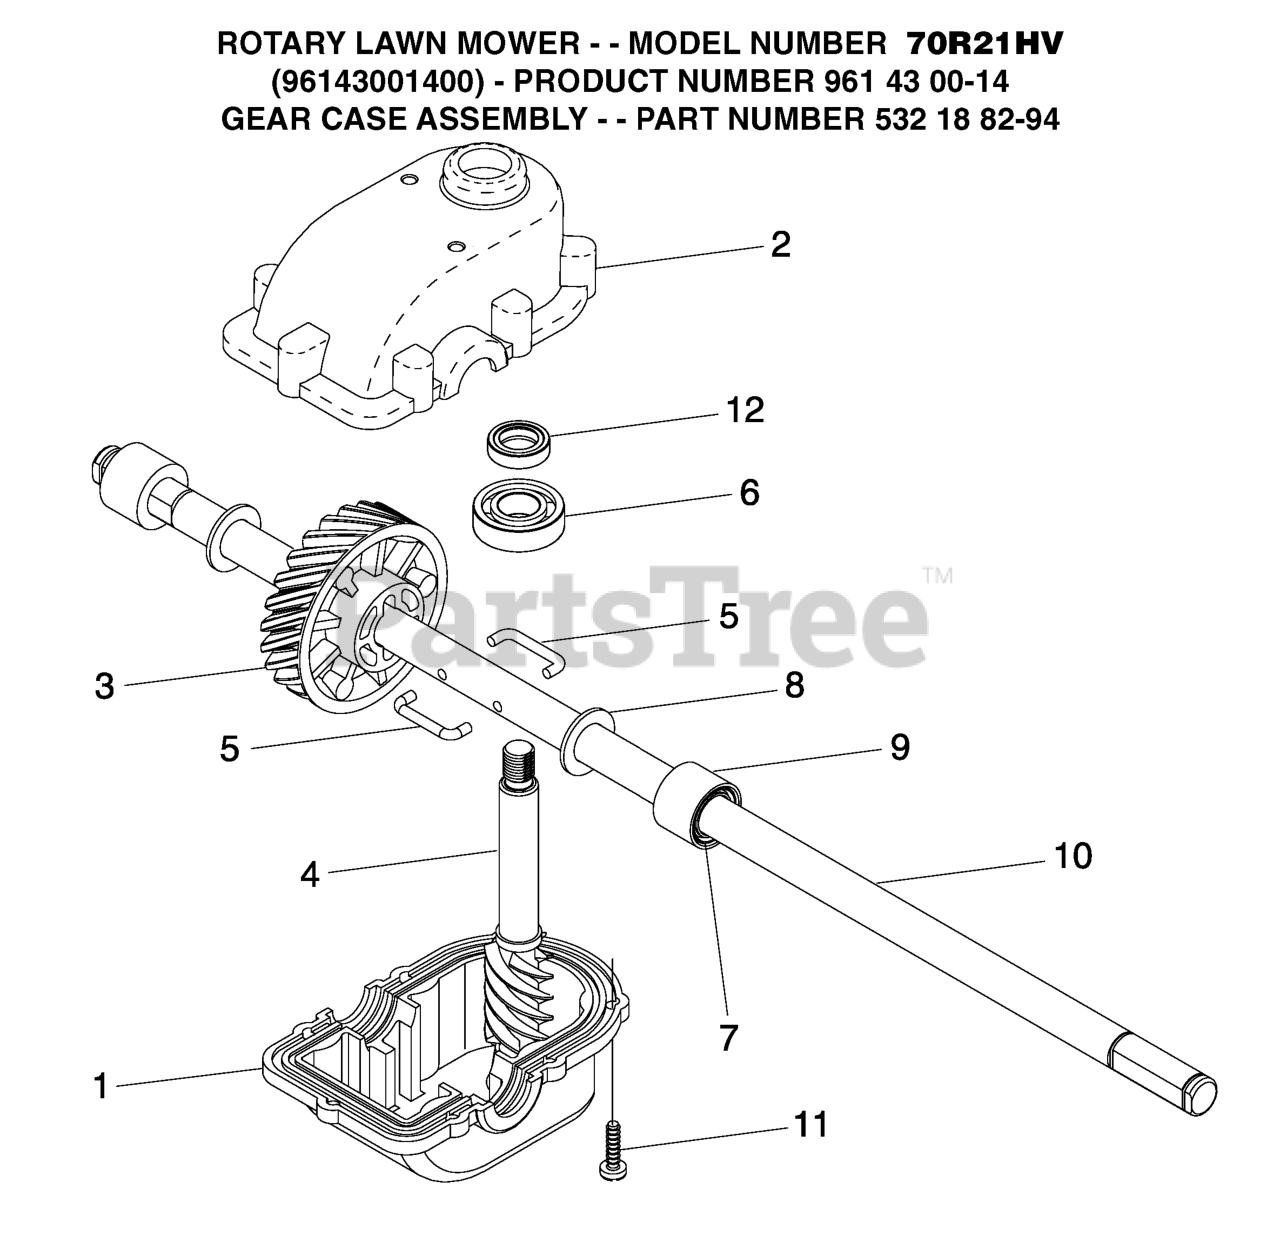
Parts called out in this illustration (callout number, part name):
1	CASE, LOWER
2	GEARCASE.HOUSING
3	GEAR.24.TOOTH.WALK.MOWER
5	WIRE, FORMED (15966)
7	SEAL.OUTPUT.SHAFT
10	SHAFT OUTPUT
12	SEAL INPUT SHAFT
